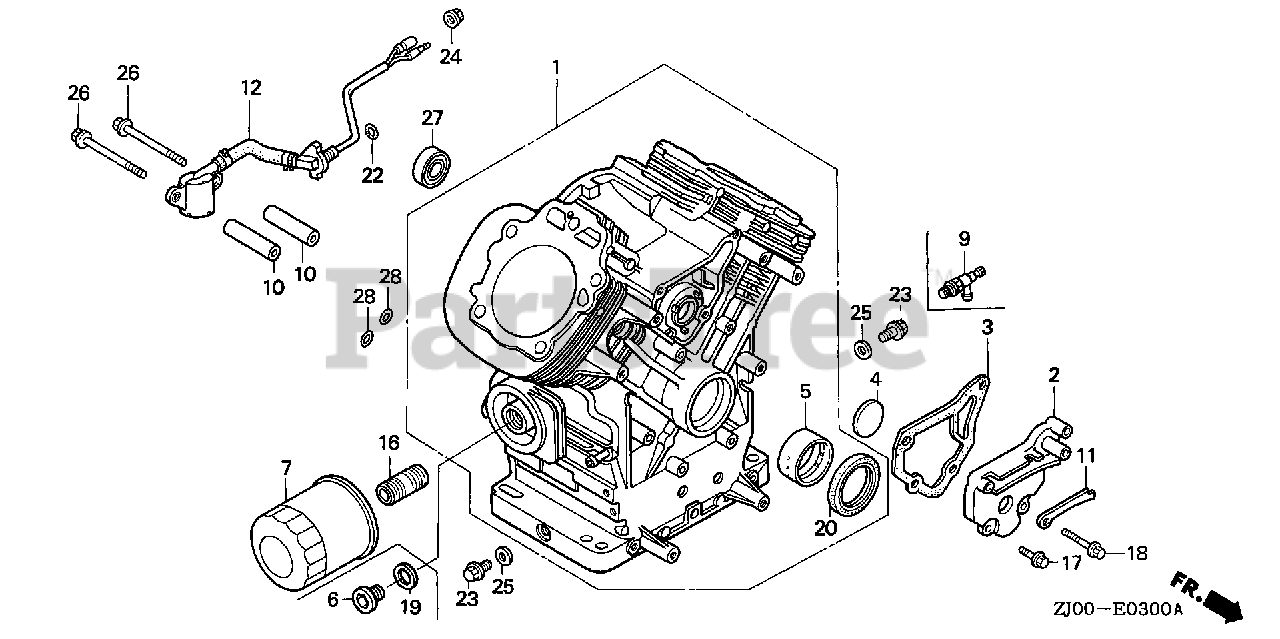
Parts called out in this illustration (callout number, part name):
1	CYLINDER ASSY.
2	COVER, BREATHER
3	GASKET, BREATHER COVER
4	VALVE, BREATHER
5	BEARING A, MAIN (BLUE) (TO SELECT CORRECT BEARING, SEE THE SERVICE MANUAL.)
5	BEARING B, MAIN (BLACK) (TO SELECT CORRECT BEARING, SEE THE SERVICE MANUAL.)
5	BEARING C, MAIN (BROWN) (TO SELECT CORRECT BEARING, SEE THE SERVICE MANUAL.)
7	FILTER, OIL (FILTECH TOYO ROKI) (SOLD INDIVIDUALLY)
7	FILTER, OIL (TOYO ROKI) (SOLD INDIVIDUALLY)
9	VALVE, DRAIN (14X1.5)
10	COLLAR, FILTER SETTING
11	CLAMP, WIRE
12	SWITCH ASSY., OIL LEVEL
16	HOLDER, OIL FILTER
17	BOLT, FLANGE (6X16) (CT200)
18	BOLT, FLANGE (6X32) (CT200)
20	OIL SEAL (38X58X11)
22	O-RING (13.5X1.5) (ARAI)
22	O-RING (14MM) (NOK)
23	BOLT, DRAIN PLUG (14MM)
24	NUT, FLANGE (10MM)
25	WASHER, DRAIN PLUG (14MM)
26	BOLT, FLANGE (6X75)
27	BEARING, RADIAL BALL (6003)
